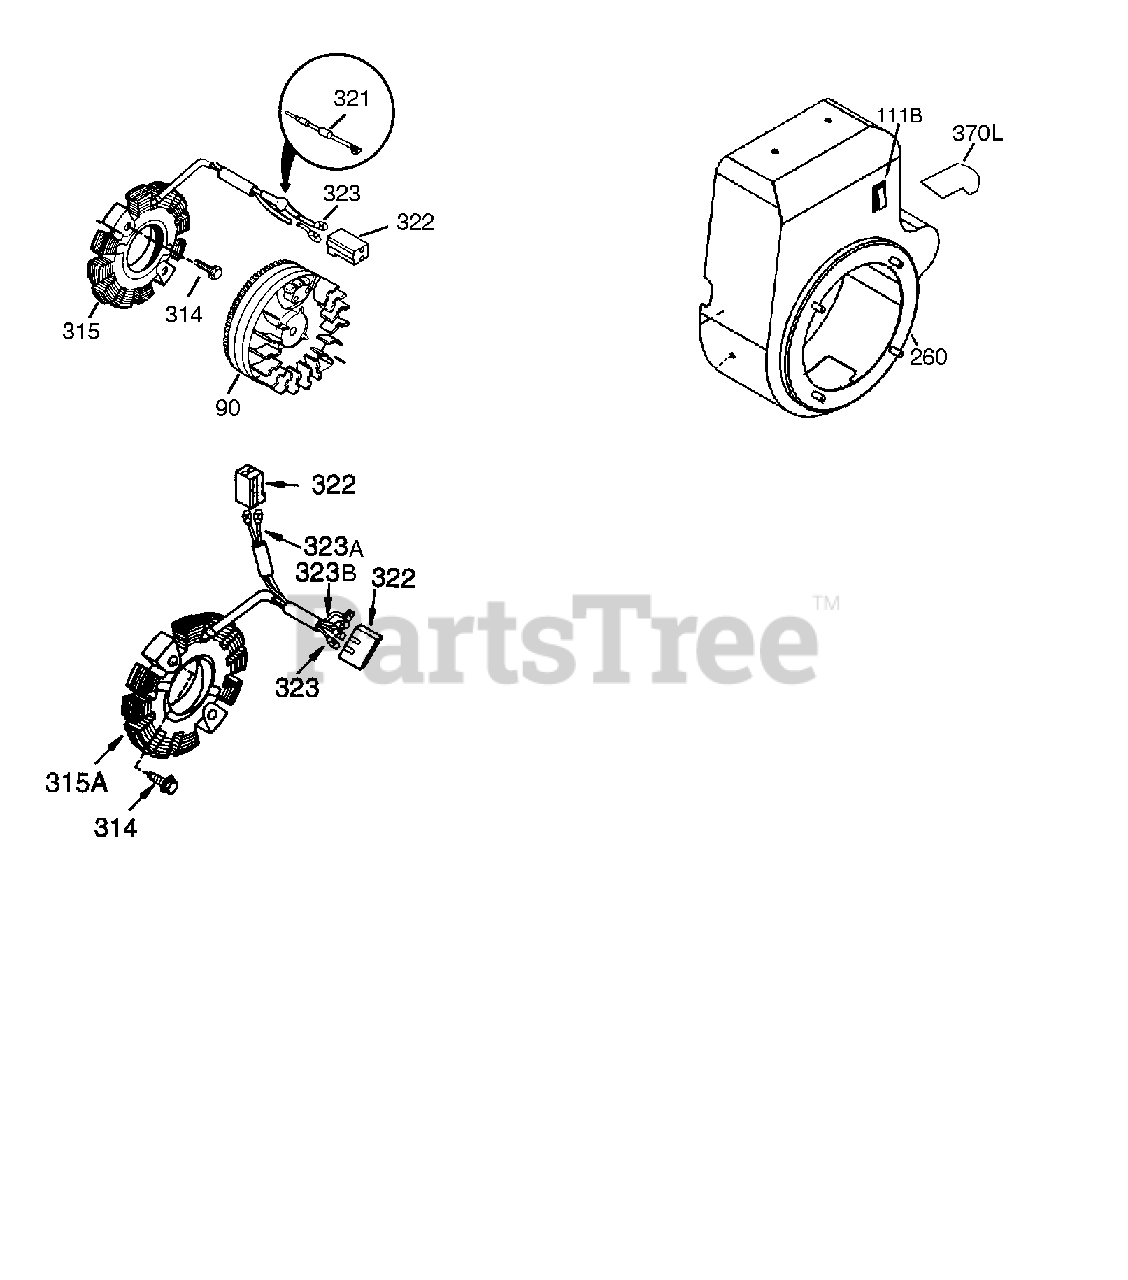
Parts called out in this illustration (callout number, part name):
62	Screw, 8-32 x 3/8"
72A	Oil Drain Plug (Sq. hd., 1/4-18)
90	Flywheel (No Ring Gear)
157A	Rocker Arm Stud/Bearing Kit (incl. re f. 155, 156, & 157)
178	Nut & Lock Washer 1/4-28
178	Nut & Lock Washer, 1/4-20
260	Blower Housing
277A	Screw, 5/16-18 x 4-1/2"
338	Screw, 10-32 x 1/2"
338	Screw, 10-32 x 5/16"
370	Decal - Tecumseh Logo for Top of Reco il Starter
370	Decal - Climate Guard This side out f or use ABOVE 32 Degrees F.
370	Decal - Climate Guard This side out f or use BELOW 32 Degrees F.
370J	Speed Control Decal
